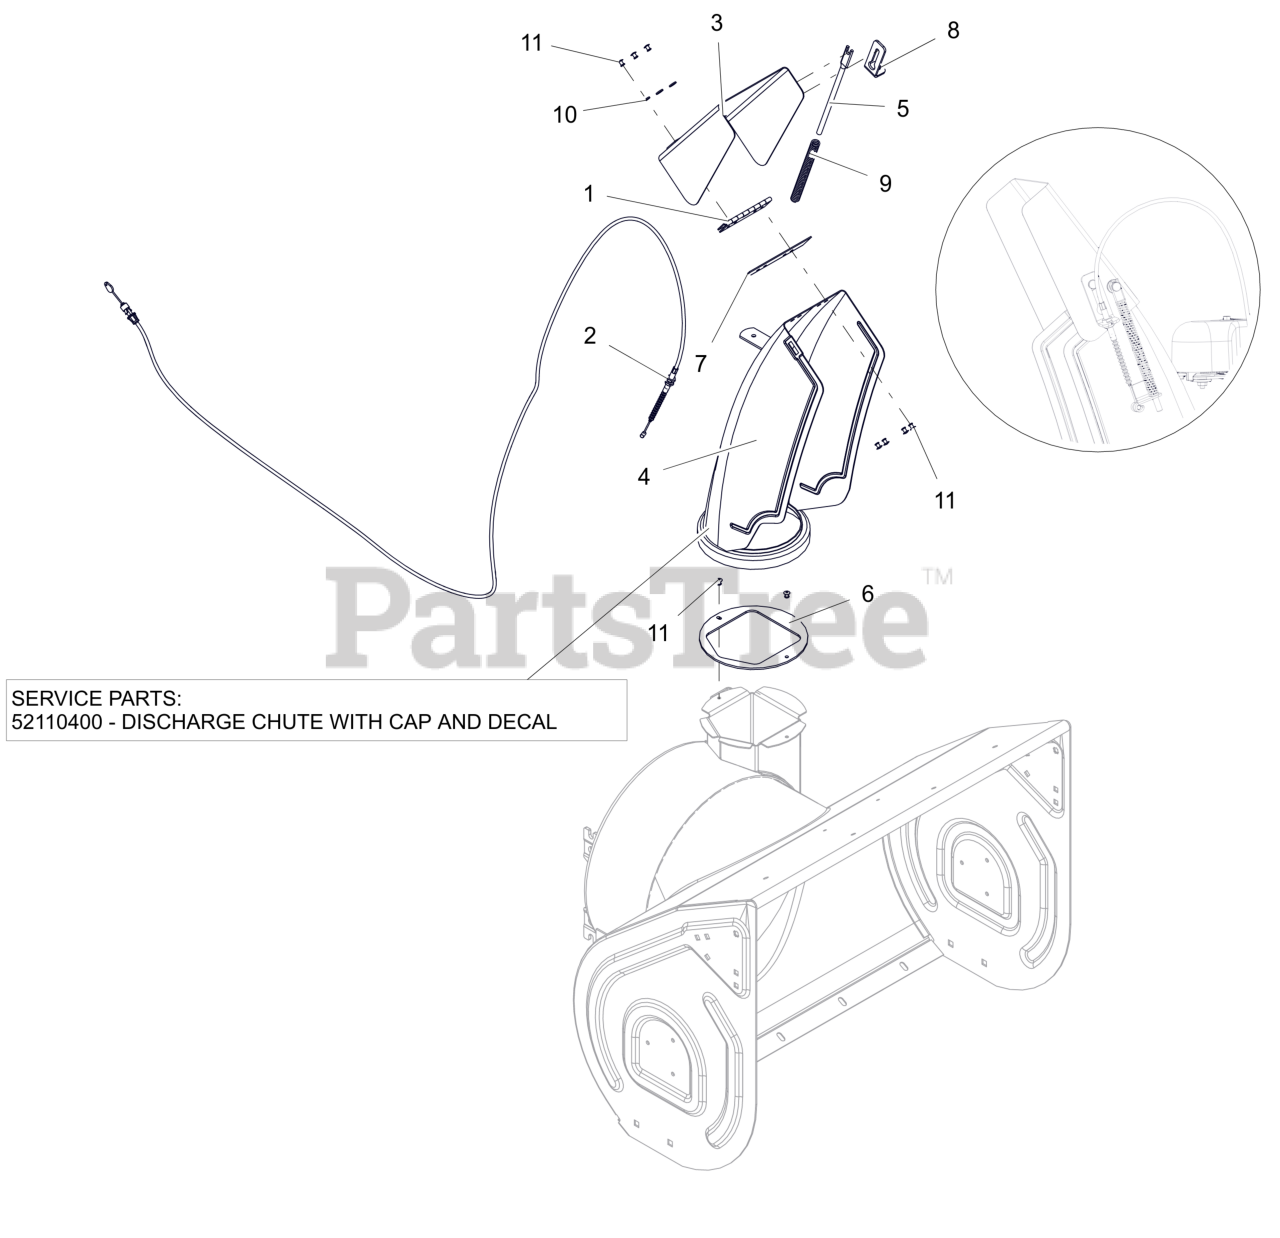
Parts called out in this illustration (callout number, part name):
1	CHUTE, DISCHARGE W/CAP
2	CABLE, DEFLECTOR - DELUXE
3	CAP, LARGE REMOTE W/DECAL
4	CHUTE,DISCHARGE,NOTCHED,QT
5	ROD, DEFLECTOR CAP
6	BAFFLE, DISCHARGE NECK
7	CAP SEAL 5.50
8	BRKT, ANCHOR - CABLE
9	SG-COMP .08X.40X6.50 14#/IN
10	WSHR,FLT .196X.500X.066 ZCC
11	RVT, POP .1875 ZCC
